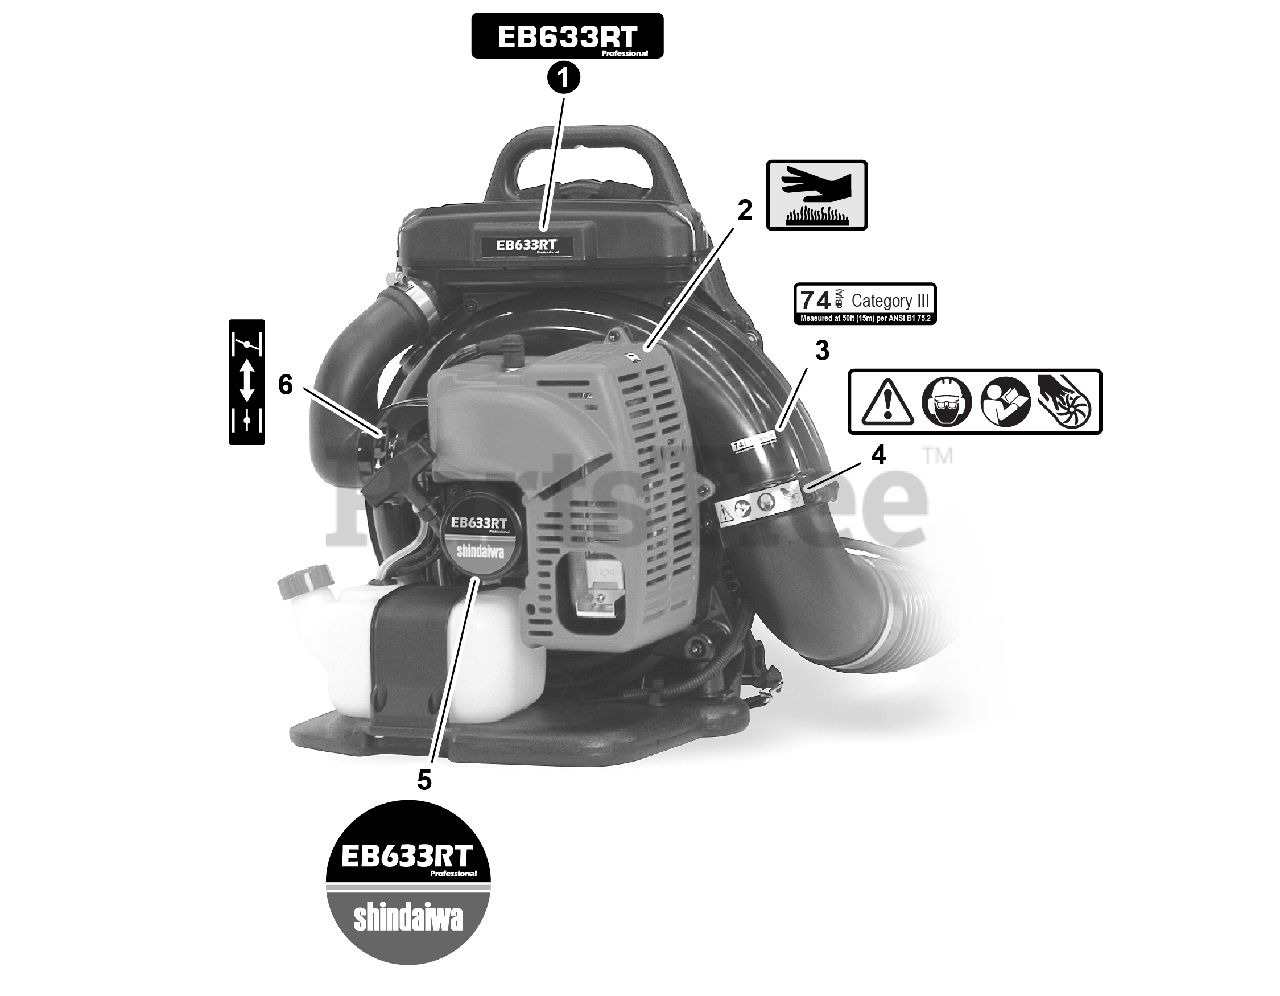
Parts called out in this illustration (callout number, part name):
1	LABEL, MODEL
2	LABEL, CAUTION - HOT
3	LABEL, NOISE
4	LABEL, CAUTION - ISO
5	LABEL, MODEL
6	LABEL, CHOKE
